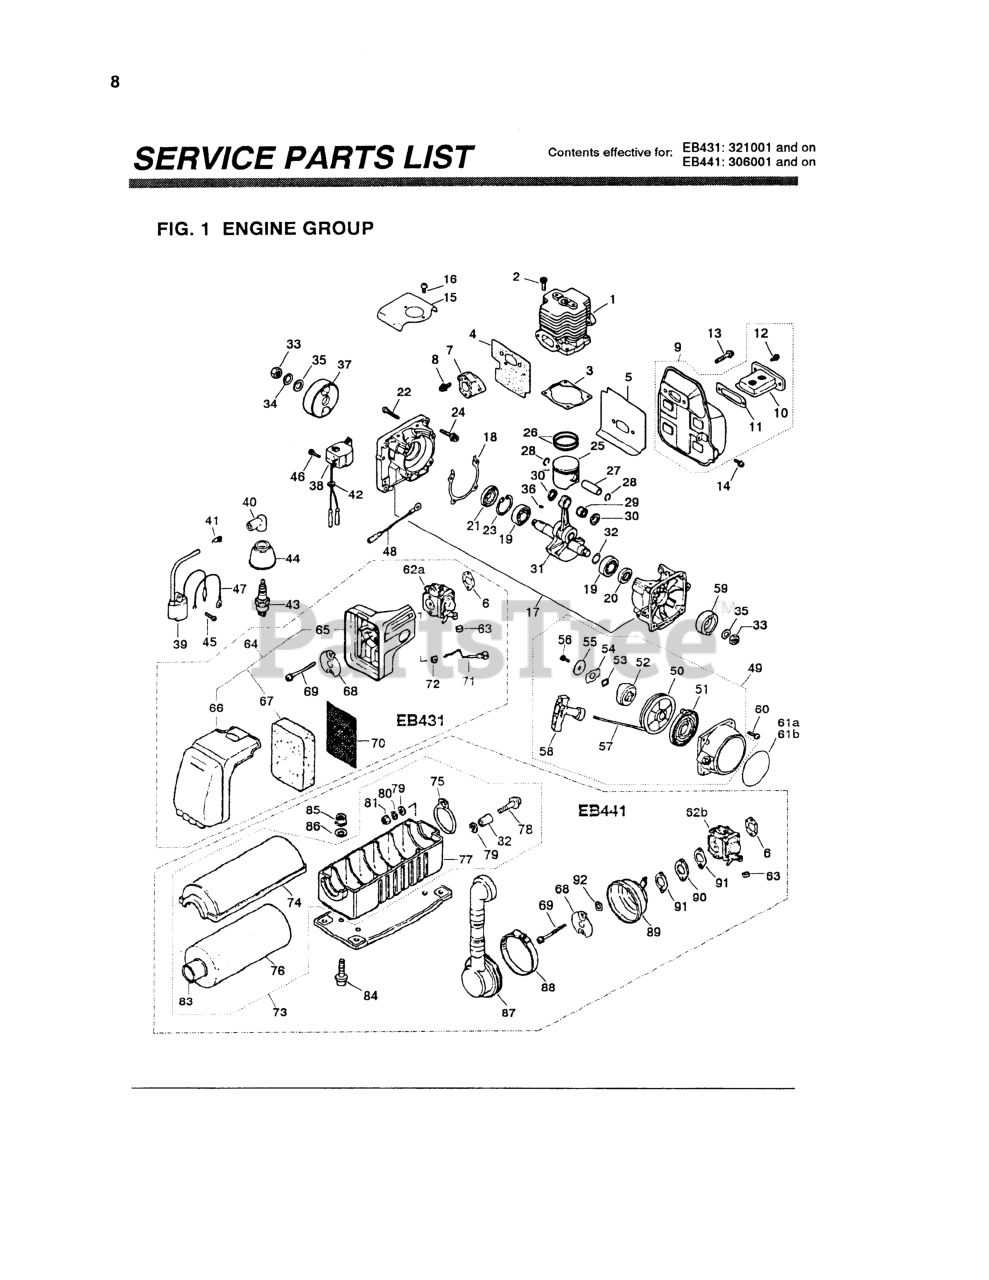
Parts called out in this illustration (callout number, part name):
8	BOLT, M5 X 25 (RPLS.1491-14120
10	ARRESTER
12	SCREW, M4 x 10
14	SCREW, M5 x 12
16	SCREW, M5 x 12
20	SEAL, OIL - STARTER SIDE
22	BOLT, M5 X 30
23	RING, SNAP, M35 X 1.5
26	RING, PISTON (RPLS -41210)
27	PIN, PISTON (RPLS. 1490-41316)
28	RING, SNAP
29	BEARING
30	WASHER (RPLS 1491-41510)
31	SHAFT (RPLS -42001)
32	SHIM (REPLACES 848-870-G000)
34	WASHER, M10 X 25
35	WASHER, M10 x 1.6
36	KEY
39	COIL, IGNITION
41	SPRING
42	GROMMET
44	CAP (NO LONGER AVAILABLE)
45	SCREW, M4 x 16
46	SCREW (REPLACES -30414)
47	CABLE COMPLETE
51	SPRING (RPLS -75220)
52	DOG
53	WASHER
54	RETAINER (RPLS 1861-75161)
55	WASHER
56	SCREW
57	ROPE
58	KNOB
59	PULLEY (RPLS -75210)
60	SCREW (USE 0263-90520 )
63	CAP, CABLE END
68	PLATE (REPLACES -82511)
69	SCREW, M5 X 55
73	CLEANER, AIR
74	COVER, CLEANER
75	BAND
76	ELEMENT
77	CASE, CLEANER
79	WASHER, M5 X .8
80	WASHER, SPRING M4 x 1.3
81	NUT, M5 X 4
82	COLLAR (NLA)
84	SCREW, M5 x 16
85	NUT (B)
86	WASHER, M5 X .8
87	HOSE (RPLS -83300)
88	CLAMP
89	CASE, CLEANER
NI	KIT, GASKET
